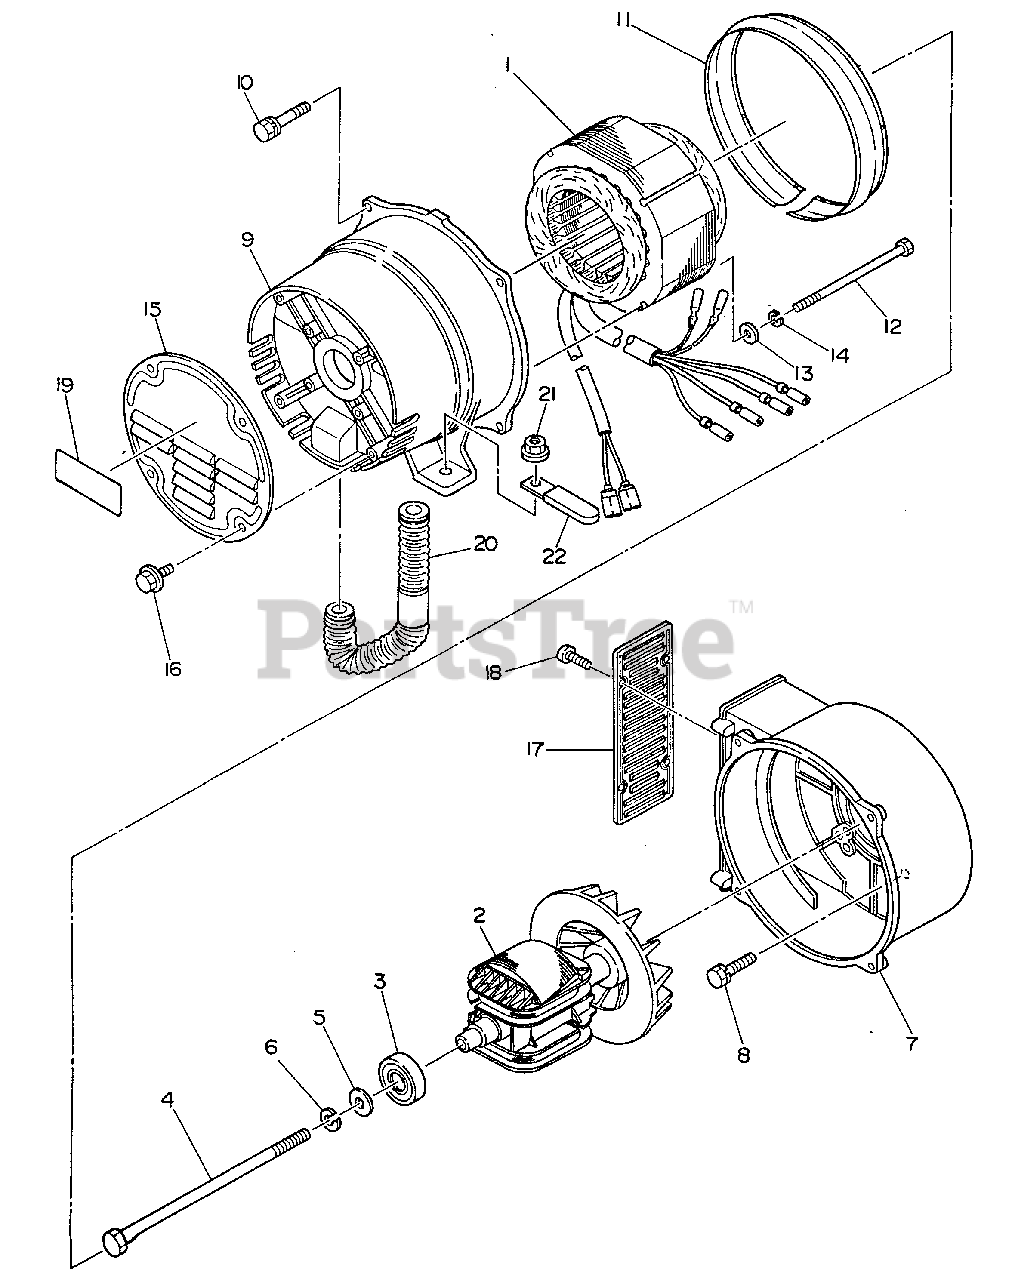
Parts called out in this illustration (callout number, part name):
1	STATOR ASSY
2	ROTOR ASSY
3	BEARING, BALL
4	THROUGH BOLT
5	WASHER
6	LOCKWASHER
7	FRONT COVER
8	BOLT
9	REAR COVER ASSY
10	BOLT
11	SUPPORT RING
13	WASHER
14	LOCKWASHER
15	END COVER
16	BOLT, FLANGE
17	FRONT PROTECTOR
18	SCREW - TAPPING
19	LABEL - GENERATOR
20	BUSHING
21	NUT, FLANGE
22	CLAMP
